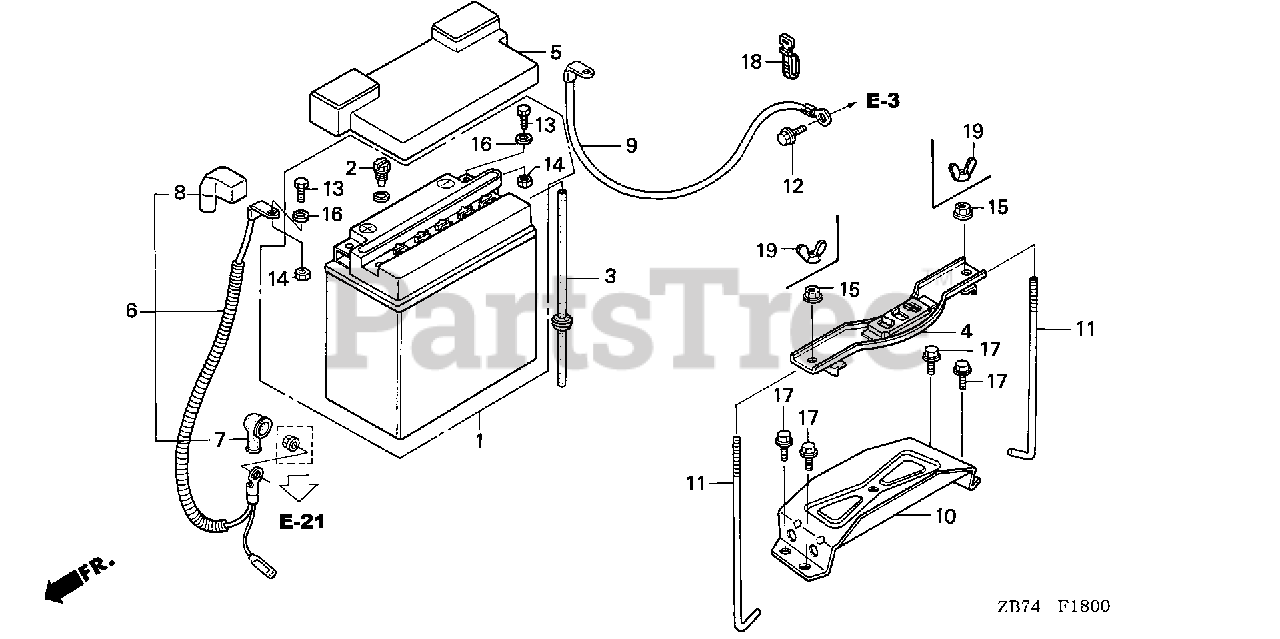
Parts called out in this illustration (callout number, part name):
1	BATTERY (YB18L-A) (YUASA)
2	PLUG, FILLING
3	TUBE, BATTERY BREATHER
4	PLATE, BATTERY SETTING
5	COVER, BATTERY
6	CABLE ASSY., STARTING
7	COVER B, MAGNETIC SWITCH (NOT AVAILABLE)
8	COVER, BATTERY TERMINAL
9	CABLE ASSY., GROUND
10	BASE, BATTERY
11	BOLT, BATTERY SETTING
12	BOLT, FLANGE (6X12) (CT200)
13	BOLT, BATTERY TERMINAL
14	NUT, BATTERY TERMINAL
15	NUT, FLANGE (6MM)
16	WASHER, BATTERY TERMINAL
17	BOLT, FLANGE (6X12) Use up to Engine SN 1543277.
18	BAND B1, CABLE Use up to Frame SN 1001879.
